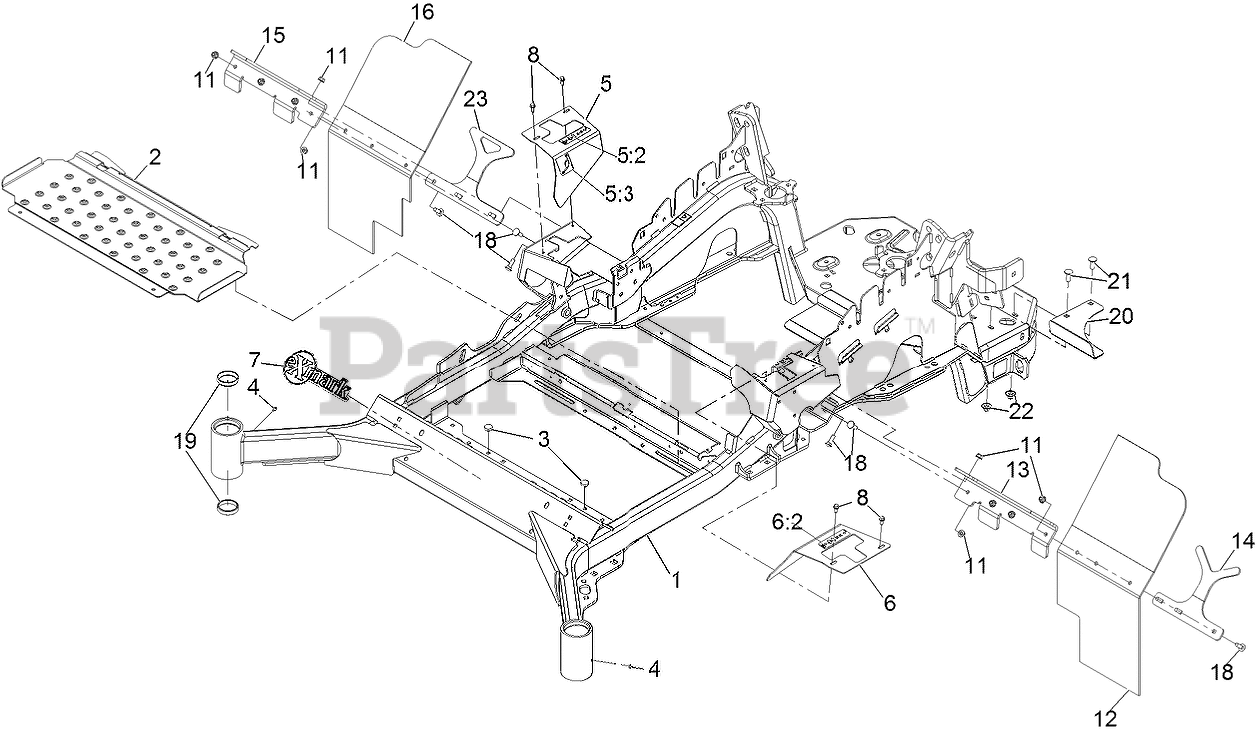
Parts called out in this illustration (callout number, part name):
1	Mainframe ASM
2	FLOOR PAN
5	RH MOTION CONTROL COVER ASM
5:2	DECAL-CONTROL, MOTION
5:3	DECAL-PARK BRAKE, CE
6	LH MOTION CONTROL COVER ASM
6:2	DECAL-CONTROL, MOTION
7	DECAL-EXMARK
8	SCREW-HWH
11	NUT-HF, NI
12	Mud Flap
13	Bracket-Mud Flap, LH
14	Support-Mud Flap, Rear
15	Bracket-Mud Flap, RH
16	Mud Flap
18	BOLT-CARR
19	CUP-BEARING
20	SHIELD-HEAT
21	SCREW-CARR
22	Nut-Nyloc 3/8-16 Flg
23	SUPPORT-MUD FLAP RH
